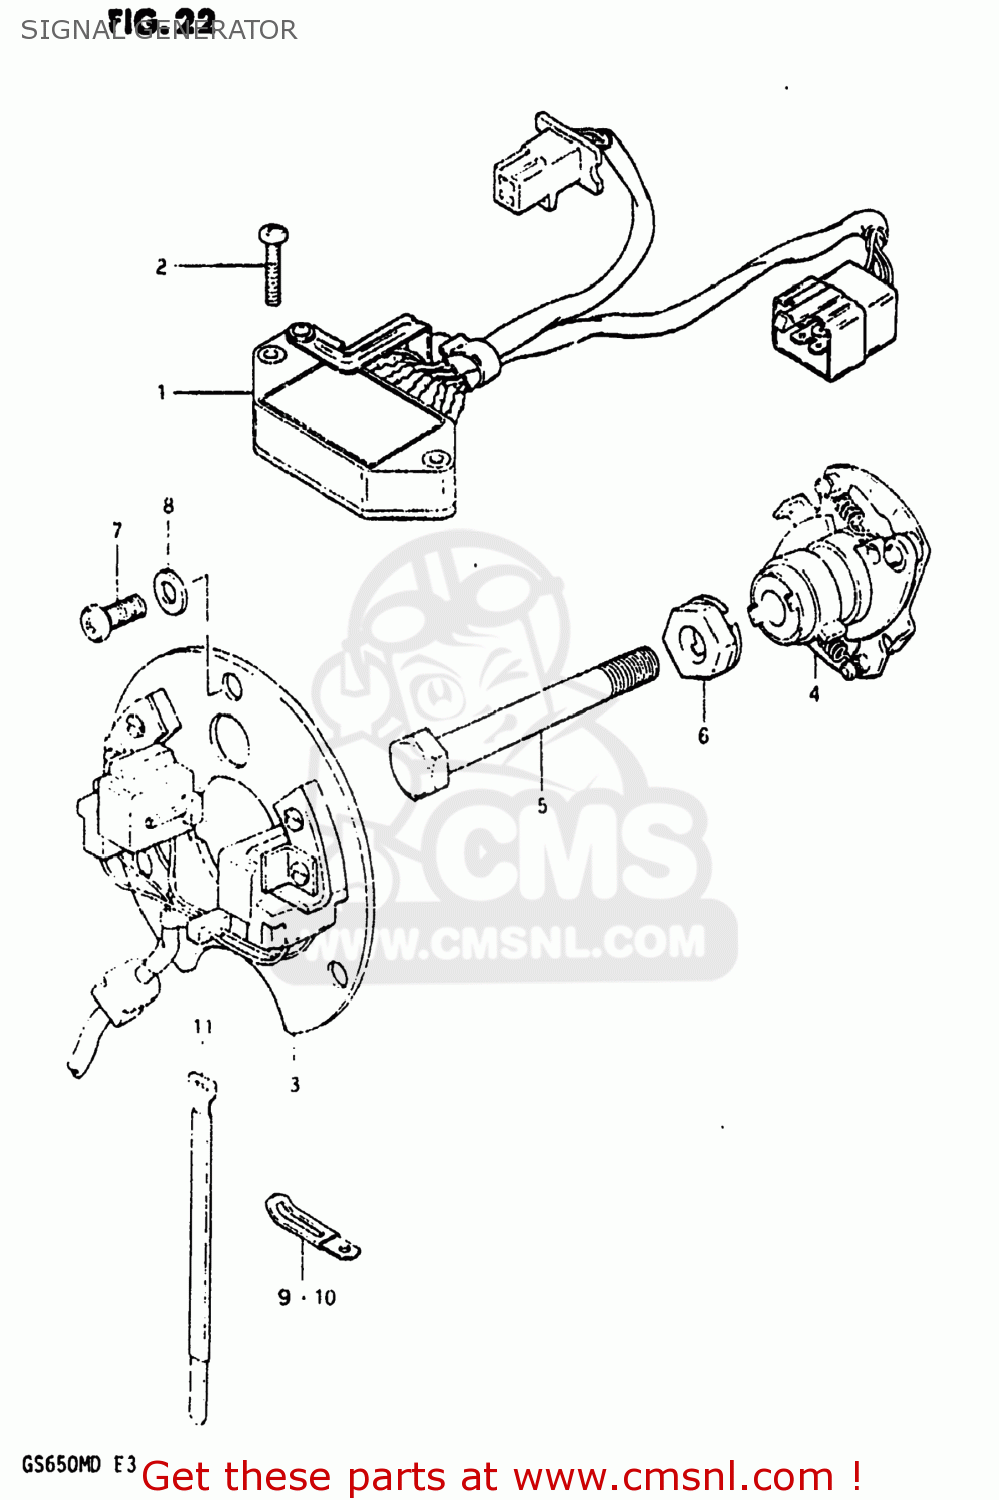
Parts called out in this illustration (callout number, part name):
1	IGNITER UNIT ASSEMBLY
2	SCREW
3	SIGNAL GENERATOR ASSEMBLY
4	GOVERNOR ASSEMBLY
5	BOLT
6	WASHER
7	SCREW(5X12)
8	WASHER
9	CLAMP L:35
10	CLAMP
11	CLAMP
